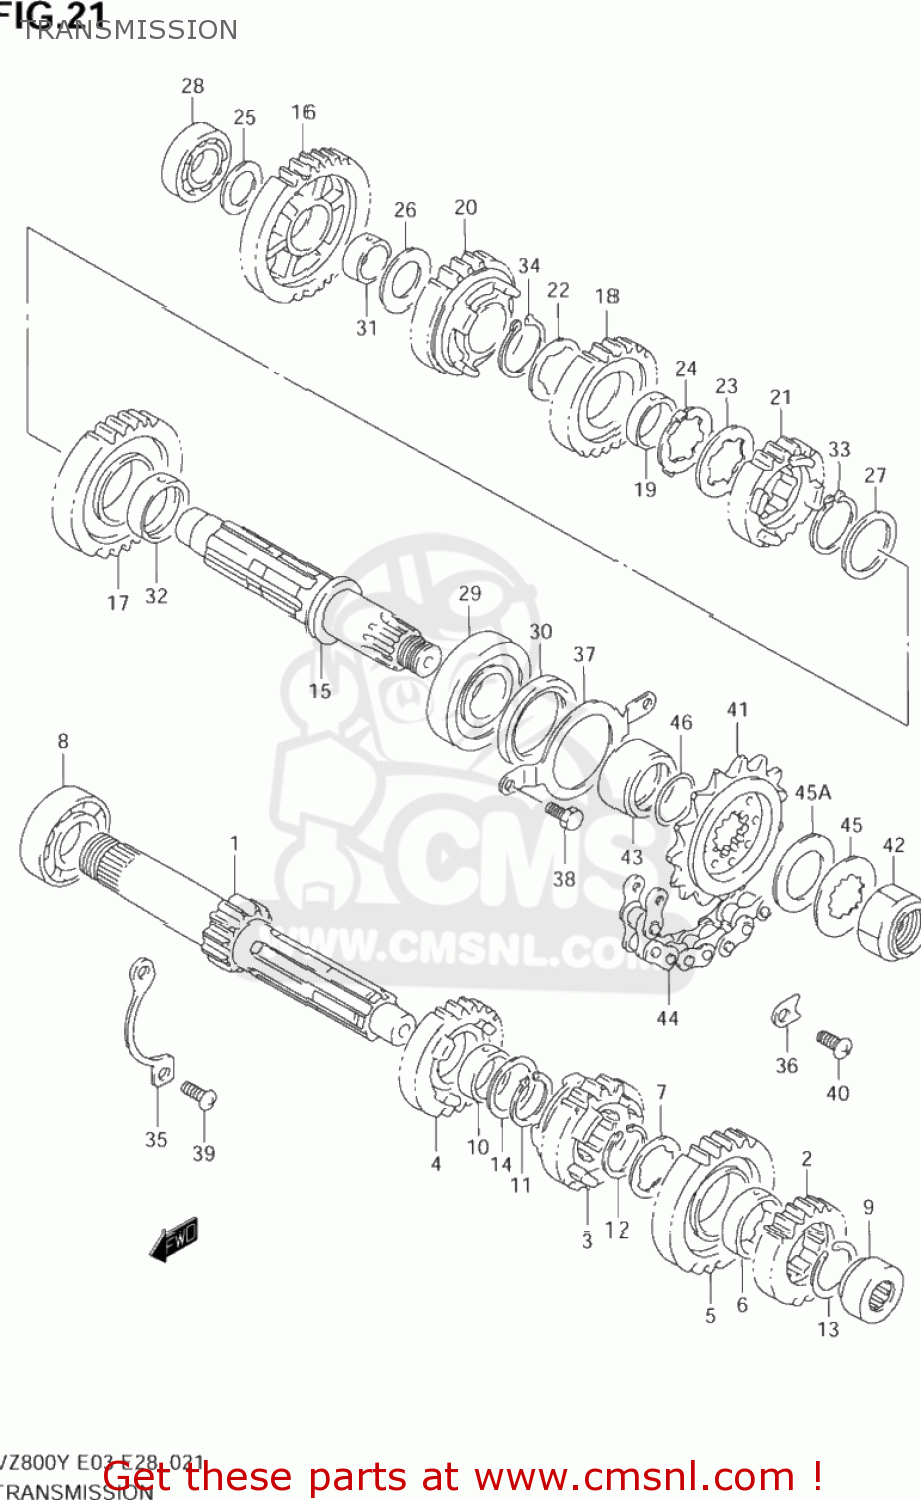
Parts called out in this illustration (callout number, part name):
1	SHAFT,COUNTER
2	GEAR,2ND DRIVE(NT:19)
3	GEAR,3RD DRIVE
4	GEAR,4TH DRIVE(NT:23)
5	GEAR,5TH DRIVE(NT:25)
6	BUSHING
7	WASHER,LOCK
8	BEARING(25X62X17)
9	BEARING(20X33X16)
10	BUSH
11	RING,SNAP
12	RING,SNAP
13	CIRCLIP
14	WASHER
15	SHAFT,DRIVE
16	GEAR,1ST DRIVEN(NT:32)
17	GEAR,2ND DRIVEN(NT:30)
18	GEAR,3RD DRIVEN(NT:24)
19	BUSH
20	GEAR,4TH DRIVEN(NT:22)
21	GEAR,5TH DRIVEN(NT:20)
22	WASHER,LOCK
23	WASHER,LOCK
24	WASHER
25	SHIM(20X32X1)
26	SHIM(22X34X1)
27	SHIM(28X36X1)
28	BEARING(20X42X12)
29	BALL BEARING 25X62X17
30	SEAL,OIL(36X50X6)
31	BUSH
32	BUSH(28X32X11)
33	CIRCLIP
34	CIRCLIP
35	RETAINER,CNTR SHAFT BEARING
36	RETAINER
37	RETAINER,DRIVE SHAFT OIL SEAL
38	BOLT
39	SCREW
40	SCREW
41	SPROCKET,ENGINE(NT:15)
42	NUT,ENGINE SPROCKET
43	SPACER,FR PULLEY
44	CHAIN(DID50VA2,116L)
45	WASHER,LOCK
45A	WASHER(25.2X42X3.2)
46	O RING(D:2.4,ID:23.7)
